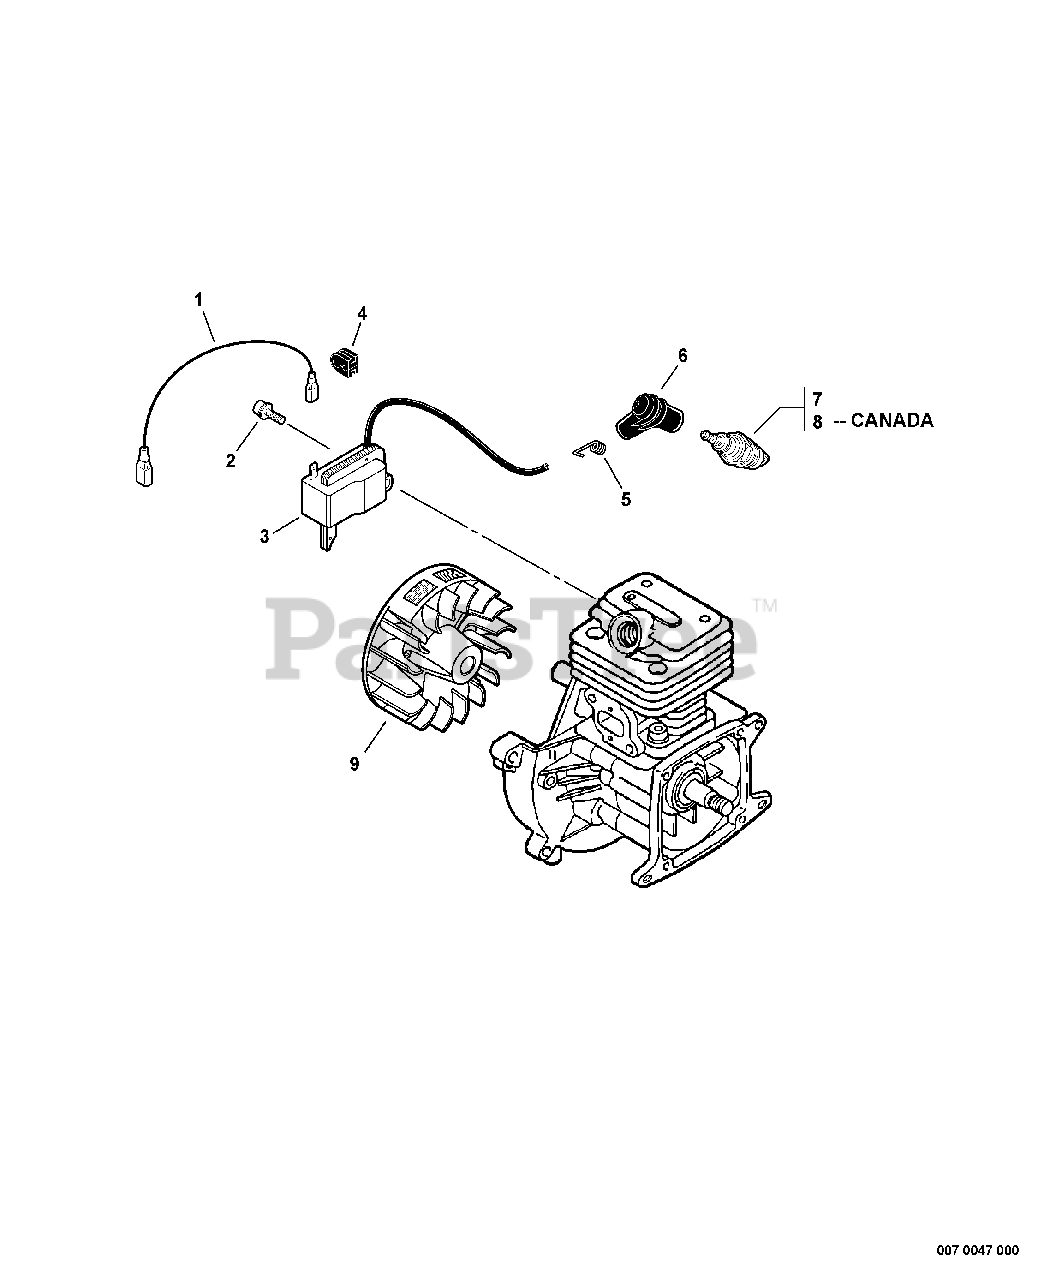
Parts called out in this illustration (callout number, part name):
1	LEAD - IGNITION
2	SCREW - 5X16
3	COIL, IGNITION
5	TERMINAL, SPARK PLUG CAP
6	CAP, SPARK PLUG
7	SPARK PLUG -- BPM-7Y
8	SPARK PLUG -- BPMR-7A
9	FLYWHEEL
